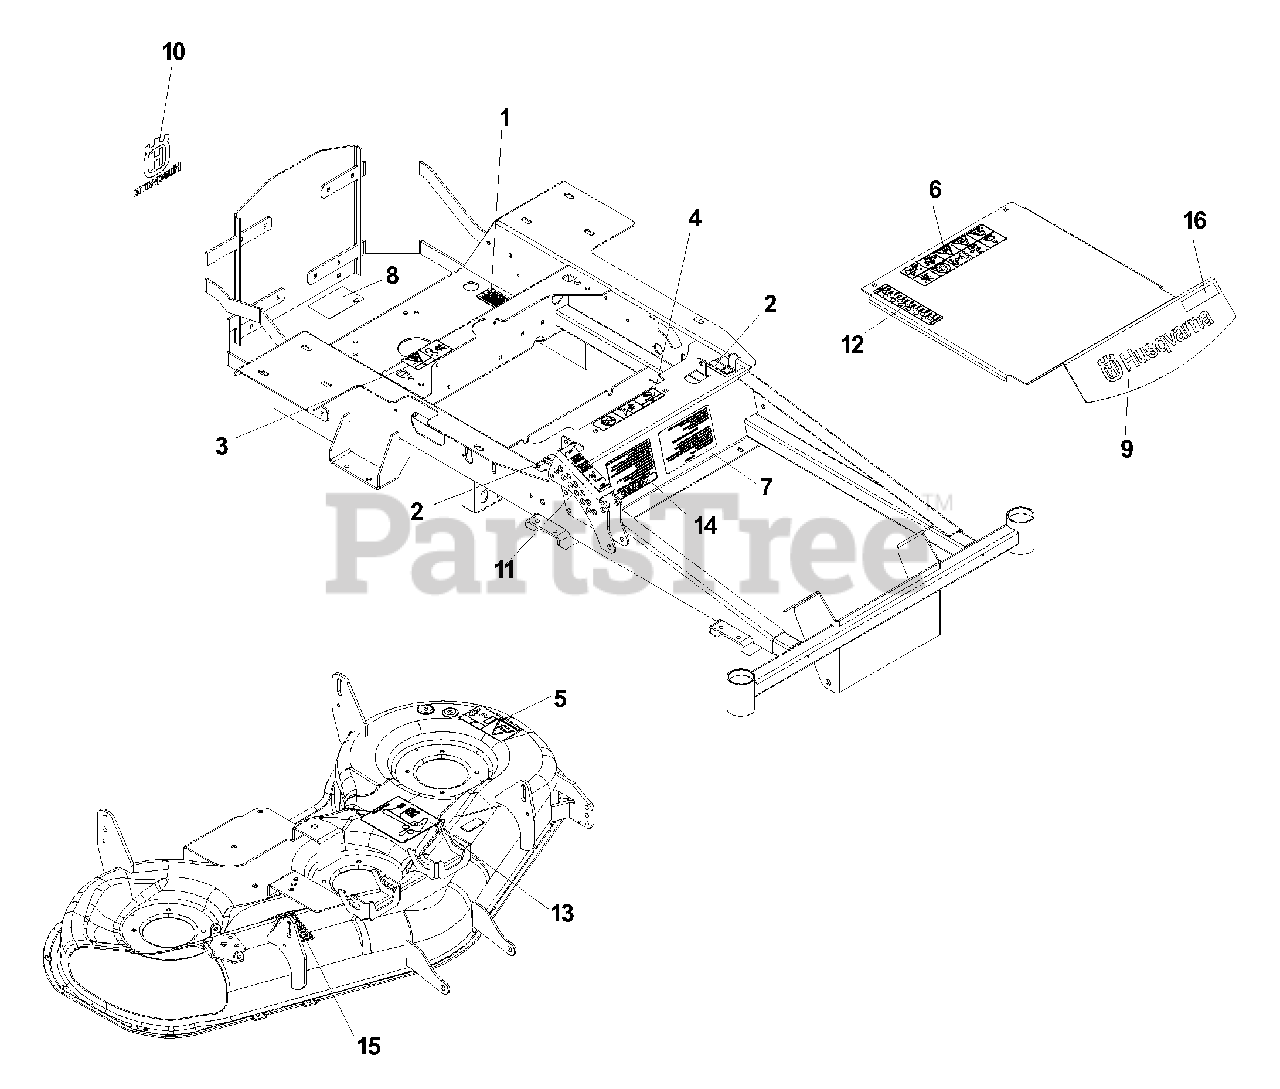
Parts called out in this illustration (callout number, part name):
1	DECAL, PROP 65
2	DECAL, MOTION CONTROL
3	DECAL, EURO DANGER BELT
4	DECAL, EURO BATTERY WARNING
5	DECAL, EURO SEVERING
6	DECAL, WARNING
7	DECAL, START
8	DECAL, DO NOT TOW
9	DECAL, HUSQVARNA
10	DECAL, CROWN
11	DECAL, TRANSPORT RELEASE
12	DECAL, HEIGHT ADJUSTMENT
13	DECAL, BELT ROUTING
14	DECAL, WARNING
15	DECAL, WARNING
16	DECAL,
